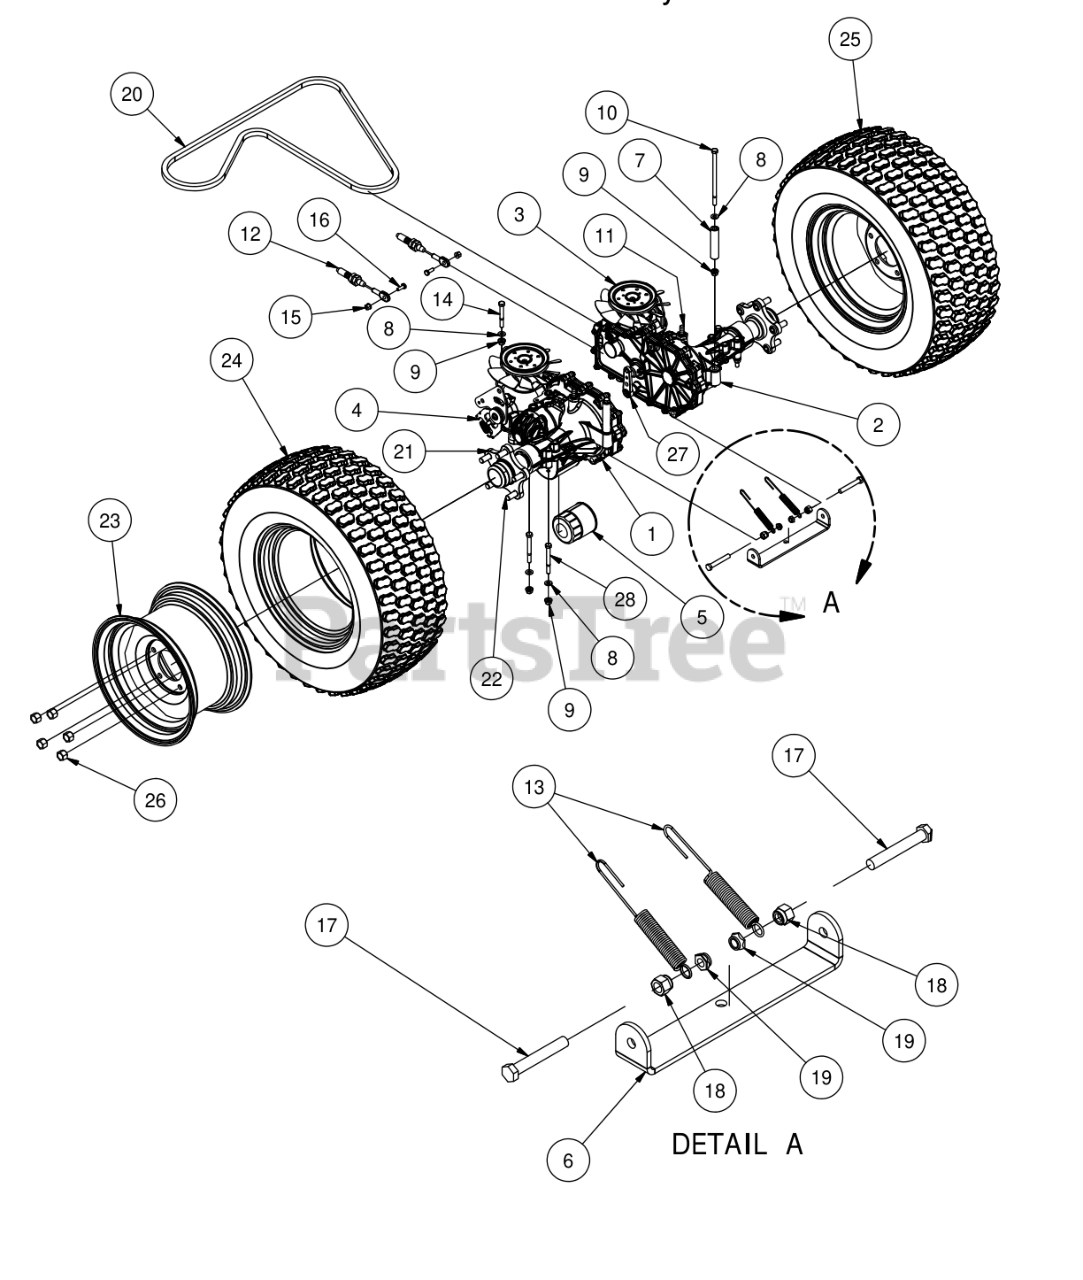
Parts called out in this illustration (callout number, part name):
1	Left 3400 IZT
2	Right 3400 IZT
3	Fan/Pully kit
4	Transaxle Spring
5	Hydraulic Filter
6	Crossover Bar for ZT 2016
7	Transaxle Spacer
8	5/16" Flat Washer
9	5/16" Nylock Flange Nut
10	5/16" x 6" Bolt
11	45 degree fitting
12	Brake Cable
13	Brake Spring
14	5/16" x 2 1/2" Bolt
15	1/4-20 Nylon Insert flange Nut
16	1/4" x 3/4" Hex Bolt
17	3/8 x 2 1/2 Hex Tap Bolt
18	3/8 Nylock Nut
19	3/8 Nylock Jam Nut 1/2 Nut
21	Transaxle Hub
22	Transaxle Wheel Studs
23	12" x 7"Black Wheel
24	23 x 8.50 -12 Tire
25	Wheel and Tire Assembly (23 and 24)
26	Acorn Lug Nut
27	Transaxle Brake Lever
28	5/16" x 3" Hex Bolt
